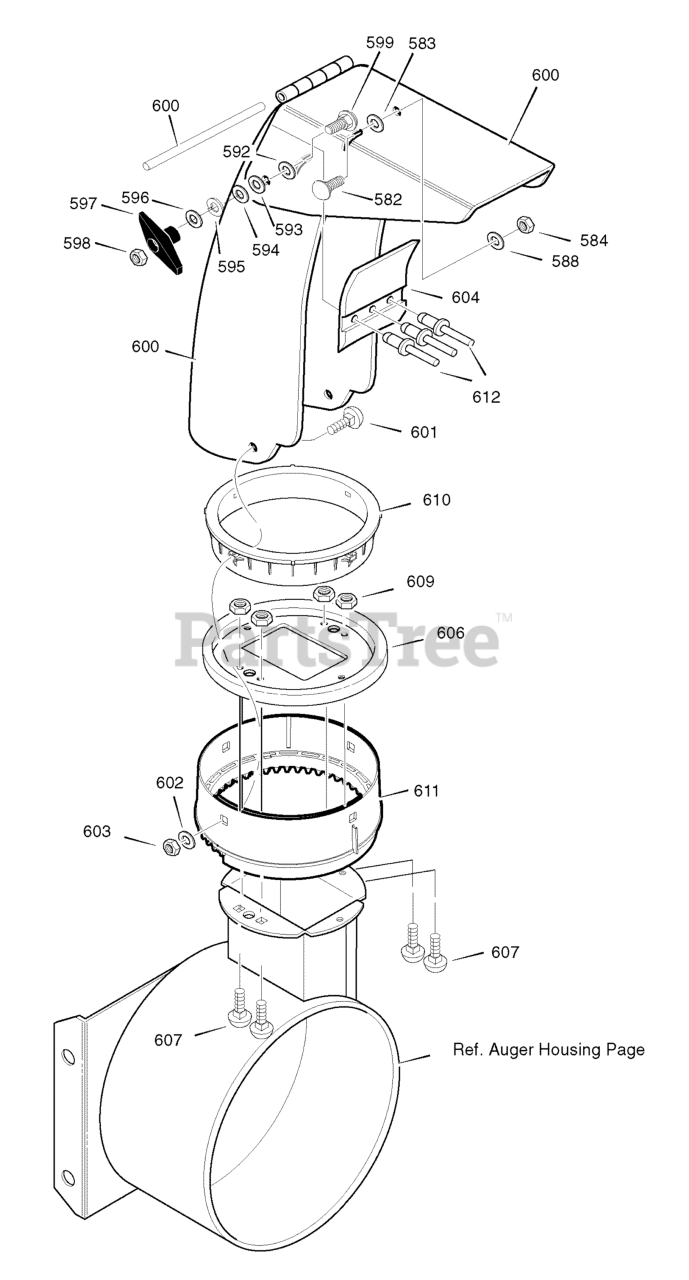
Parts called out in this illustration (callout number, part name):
582	BOLT, CARRIAGE 5/16-18 X.75
583	WASHER, PLASTIC
584	NUT, 5/16-18 REGHEX NYLOCK
588	WASHER, PLASTIC
592	WASHER, PLASTIC
593	WASHER, PLASTIC
594	WASHER, FLAT
595	WASHER, SPLIT
596	WASHER, FLAT
597	KNOB, T 3.00
598	NUT, 5/16-18 REGHEX
599	BOLT, 5/16-18X1.00
600	CHUTE ASSEMBLY
601	BOLT, 5/16-18 X1.00
602	WASHER, FLAT
603	NUT, 5/16-18 HEXNYL
604	FLAP, CHUTE
606	CHUTE COLLAR
607	SCREW, 1/4-20 X 0.75
609	NUT, 1/4-20 HEX NYLOCK
610	RETAINER RING INNER
611	RETAINER RING OUTER
612	RIVET, POP ALMUMINUM 1/8 X 1/4
